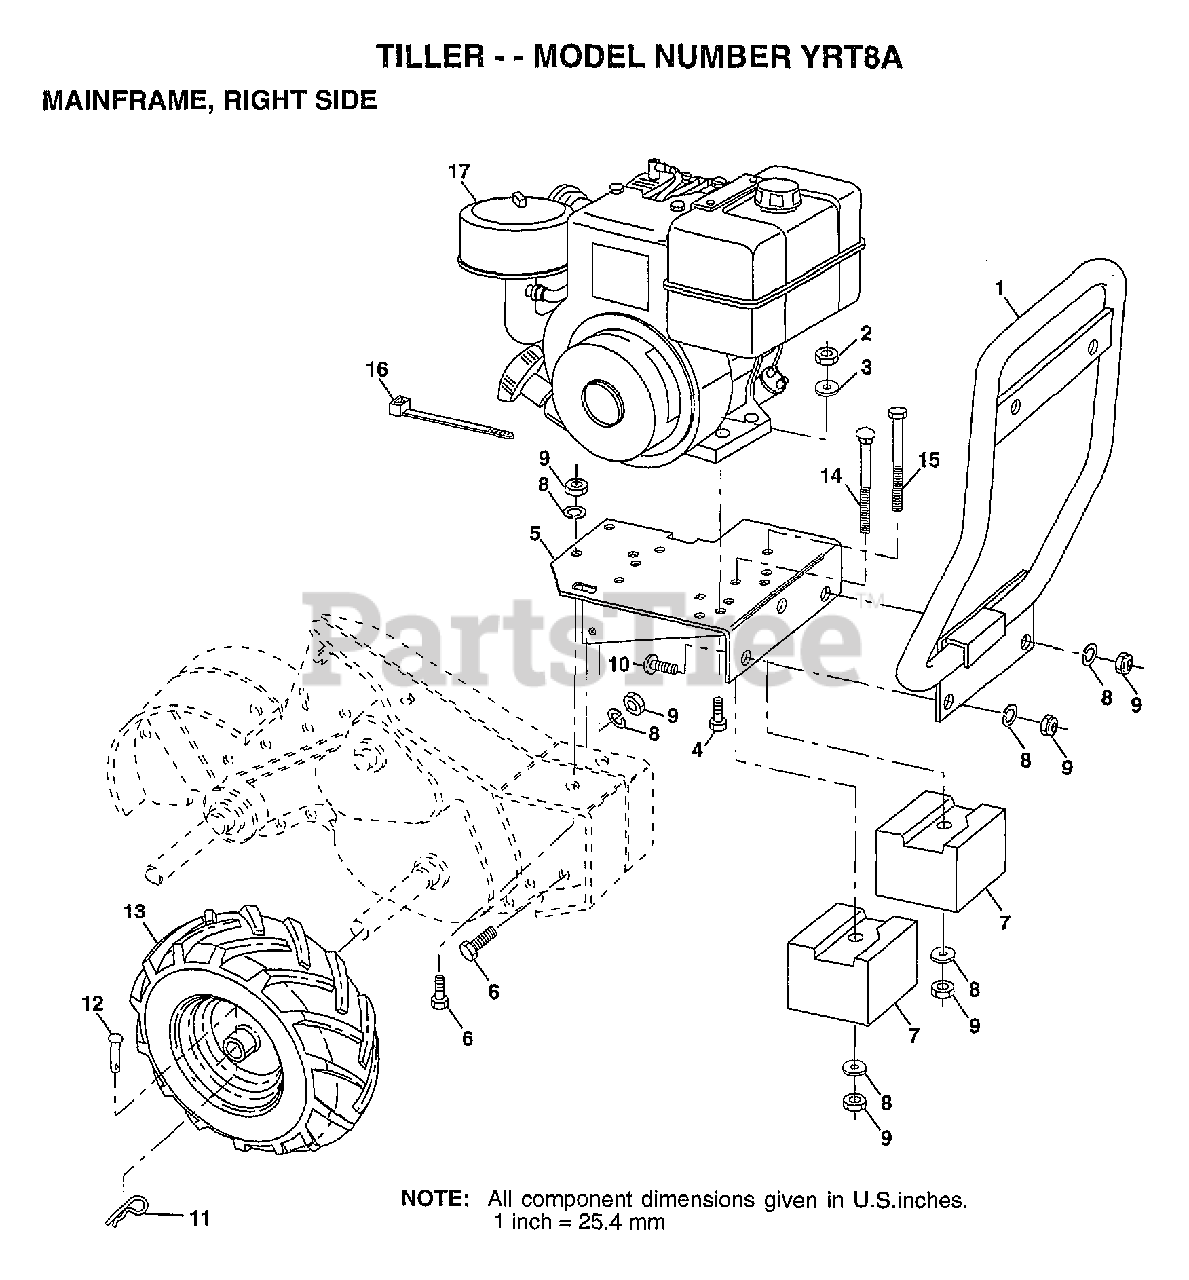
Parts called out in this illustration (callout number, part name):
1	BUMPER.ASM
2	NUT.HEX.5/16-18
3	LOCKWASHER
4	BOLT
5	"ASM. ENGINE, BASE"
6	BOLT
7	COUNTERWEIGHT CRT
8	LOCKWASHER
9	NUT.HEX.3/8-16UNC
11	SPRING.RETAINER
12	RIVET.PAN HD.1.75
13	TIRE TI
13	WHEEL TI
14	BOLT CRT
15	BOLT.3/8-16X4.5
16	TIE CABLE CRT
